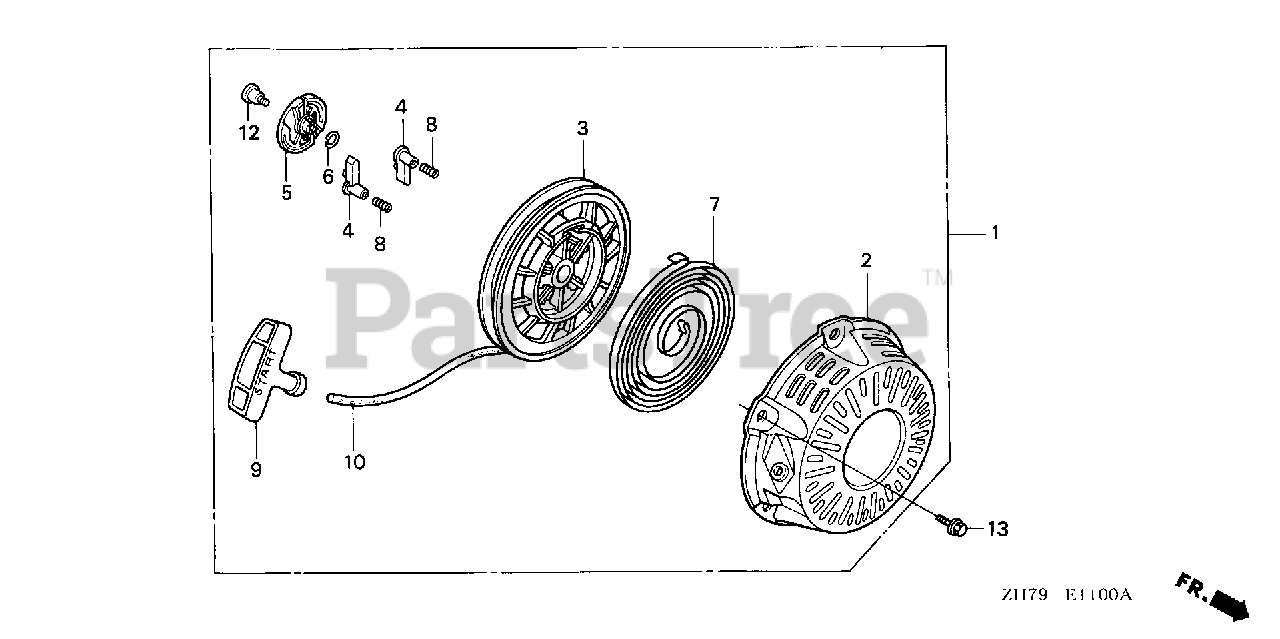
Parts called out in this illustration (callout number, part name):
1	STARTER ASSY., RECOIL *R8* (BRIGHT RED)
2	CASE, RECOIL STARTER *R8* (BRIGHT RED)
3	REEL, RECOIL STARTER
4	RATCHET, STARTER
5	GUIDE, RATCHET
6	SPRING, FRICTION
7	SPRING, RECOIL STARTER
8	SPRING, RETURN
9	KNOB, RECOIL STARTER
10	ROPE, RECOIL STARTER (NA USE ALT:08550-ZG921-11)
12	SCREW, SETTING
13	BOLT, FLANGE (6X10)
